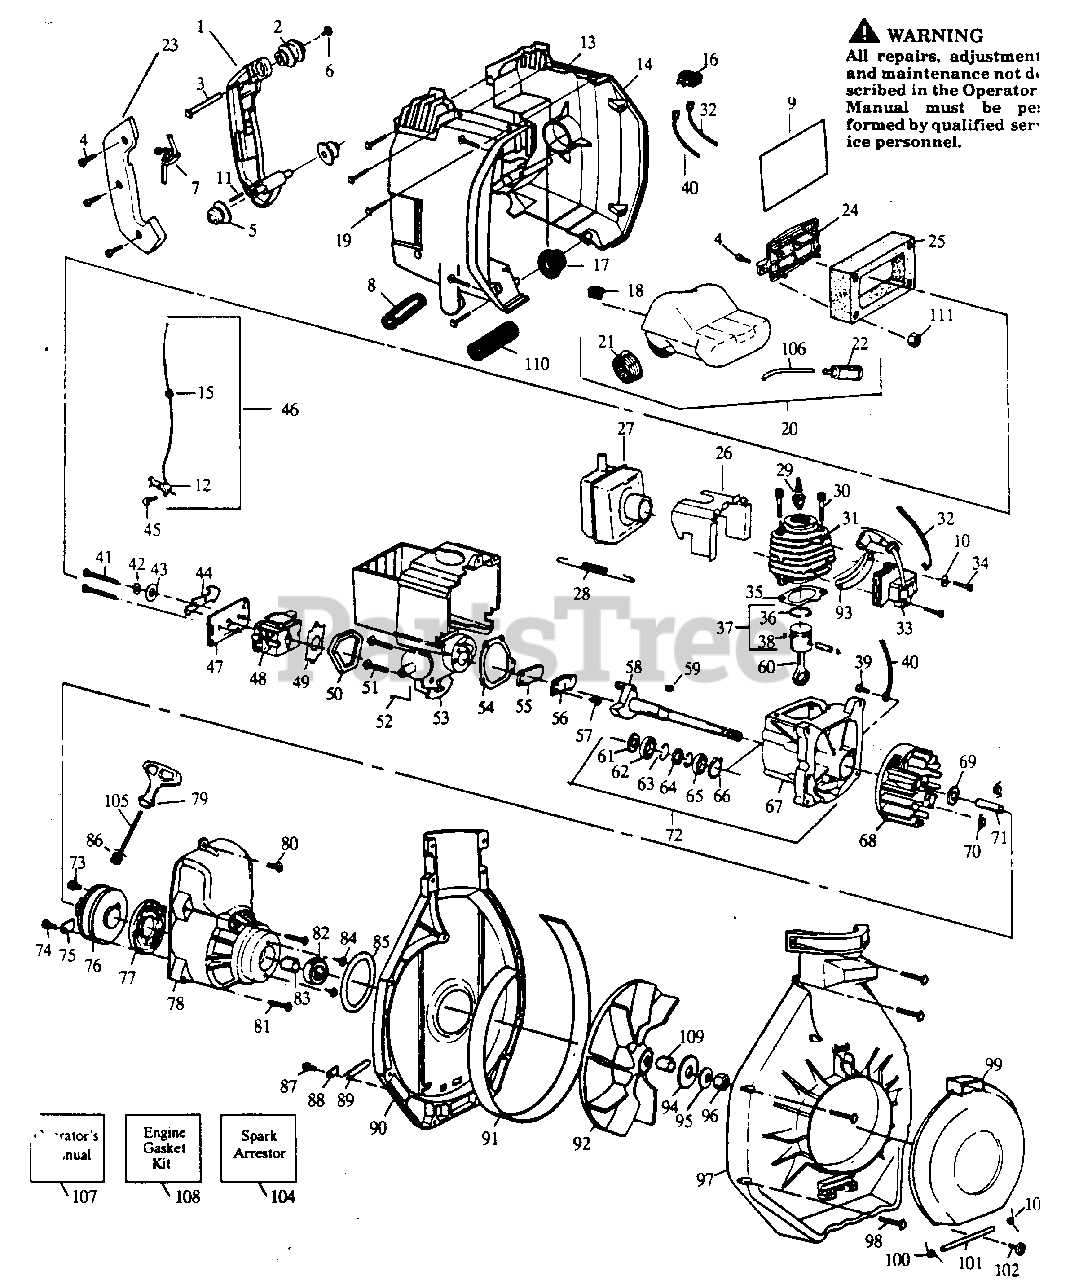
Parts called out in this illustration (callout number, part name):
2	Front Isolator
4	Screw
5	Rear Isolator
8	Assist Handle Tube
9	Instruction Decal
12	Cable Anchor
13	Shroud-Left
14	Shroud-Right
17	Isolator
18	Isolator
20	Fuel Tank Ass'y. (Inc. 21,22,106)
21	Fuel Cap (w/ retainer)
22	Fuel Pick-up Ass'y.
23	Handle Cover
25	Air Filter
26	Air Baffle
29	Spark Plug (CJ-8Y)
31	Cylinder
32	Lead Wire
33	Ignition Module
35	Gasket
36	Piston Ring
37	Piston Kit
38	Retainer
40	Ground Wire
42	Wave Washer
43	Spacer
44	Choke Shutter
46	Cable Assembly (Inc.45)
48	Carburetor
52	Ground Wire
53	Reed Block
55	Reed Valve
56	Reed Stop
58	Crankshaft
60	Piston Rod
62	Inner Bearing
63	Retaining Ring
64	Crankshaft Seal
65	Outer Bearing
66	Retaining Ring
67	Crankcase
68	Flywheel
69	Washer
72	Crankcase/Crankshaft Assy.
73	Screw
75	Retainer
76	Starter Pulley
77	Starter Spring
78	Fan Housing
79	Starter Handle
82	Bearing
84	Screw
85	"O" Ring
88	Retainer
89	Roll Pin
90	Blower Housing (Upper)
92	Impeller
97	Blower Housing (Lower)
98	Screw
99	Door
104	Spark Arrestor Kit
105	Rope Kit
106	Line Kit
107	Operators Manual
108	Gasket Kit
109	Hub
110	Foam Grip
